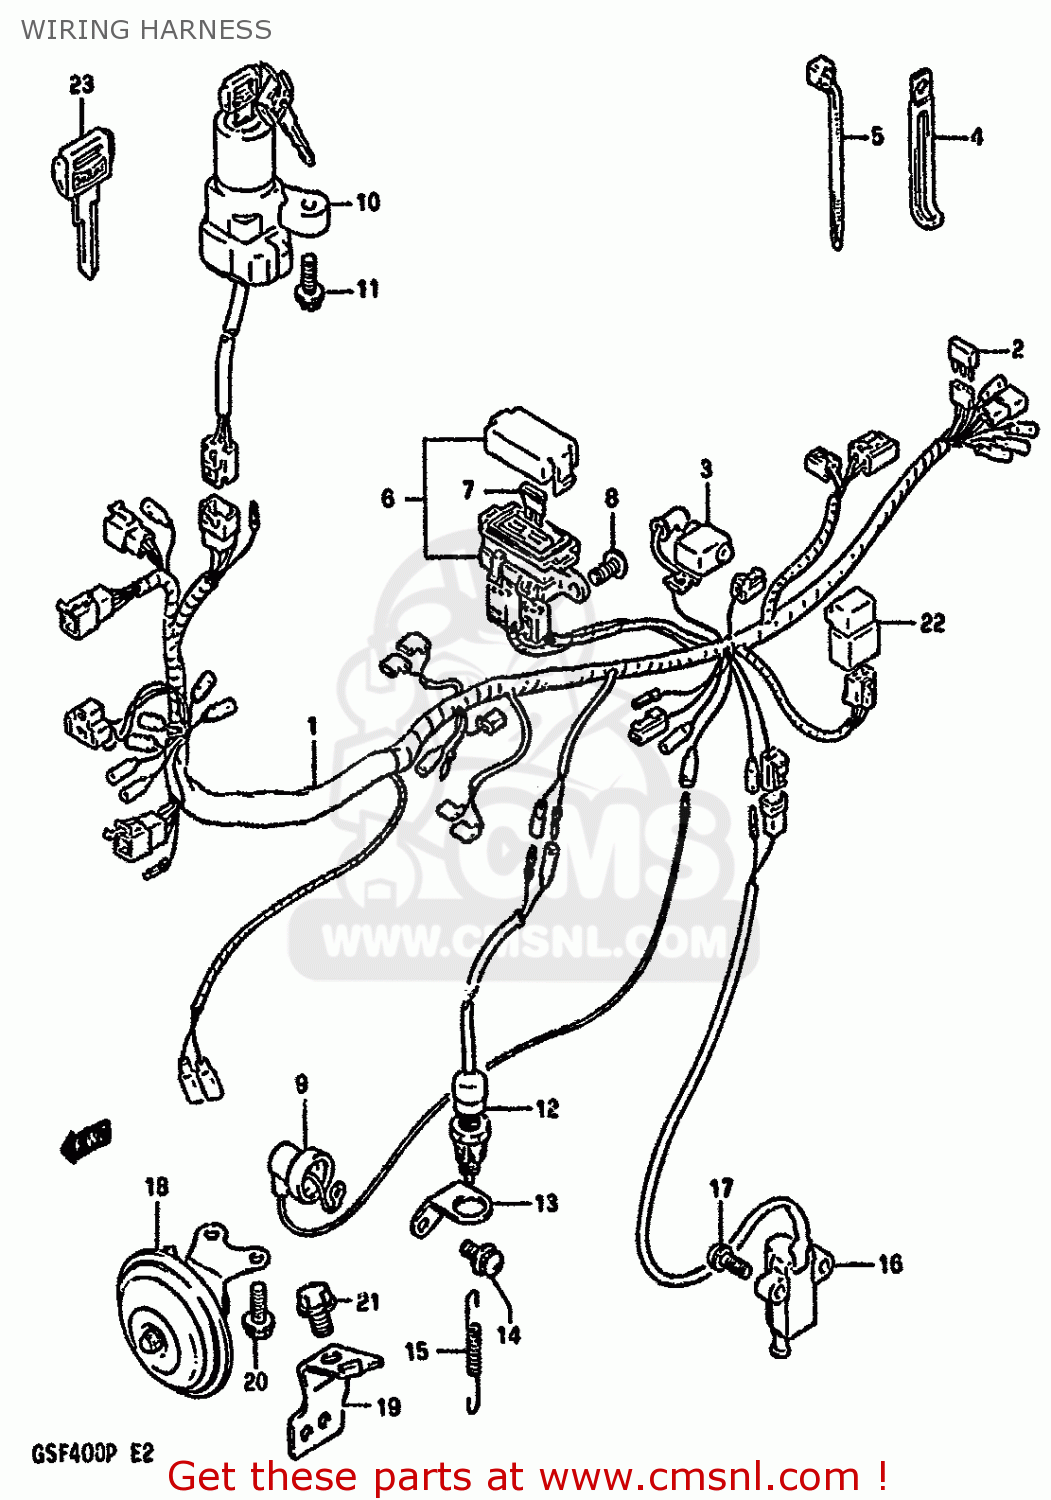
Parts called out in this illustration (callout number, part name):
1	HARNESS,WIRING
2	DIODE(STANLEY DE8804)
3	CAP,BATTERY PLUS
4	CLAMP
5	CLAMP
6	BOX ASSEMBLY,FUSE
7	FUSE(10A)
8	SCREW
9	WIRE
10	LOCK ASSEMBLY,STEERING
11	SCREW(6X18)
12	SWITCH ASSEMBLY,STOP LAMP
13	BRACKET,STOP LAMP SWITCH
14	SCREW
15	SPRING
16	SWITCH ASSEMBLY,SIDE STAND
17	BOLT 6X20
18	HORN ASSEMBLY
19	BRACKET,HORN
20	BOLT
21	BOLT
22	RELAY ASSEMBLY
23	KEY,BLANK
